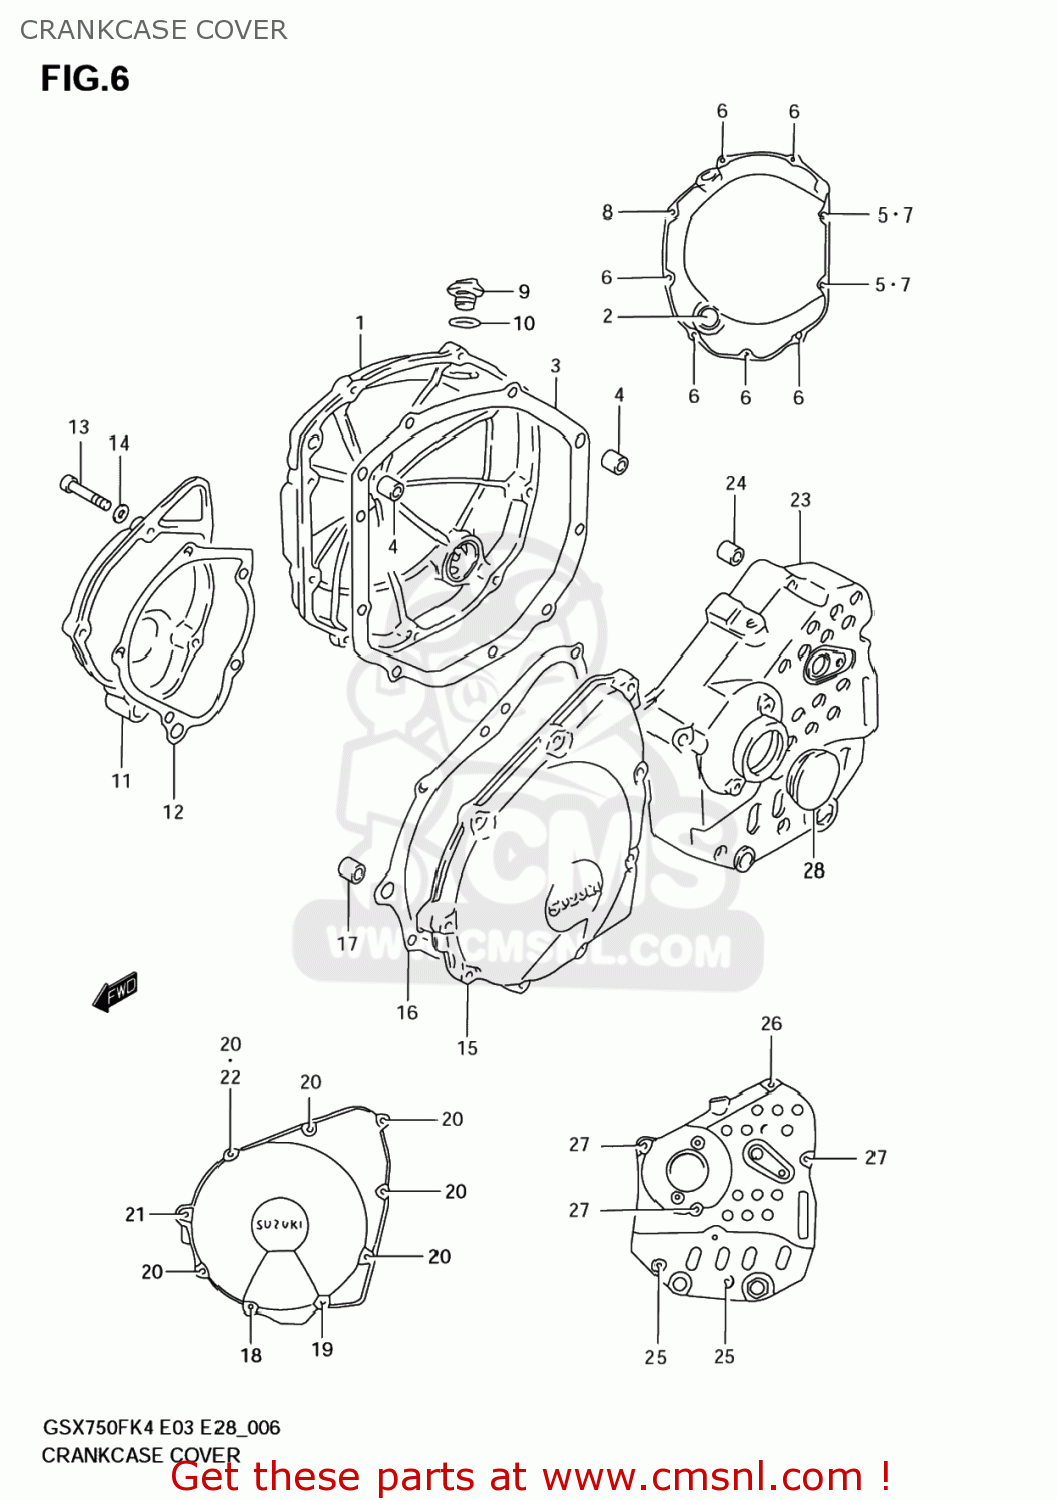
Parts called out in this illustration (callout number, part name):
1	COVER,CLUTCH
2	LENS,OIL LEVEL CHECK
3	GASKET,CL COVER (NAS)
4	PIN
5	GASKET(5.8X13X1.2) (NAS)
6	BOLT(6X25)
7	BOLT
8	BOLT
9	PLUG,ENGINE OIL FILLER
10	O RING(D:3.1,ID:16.8)
11	COVER,SIGNAL GENERATOR
12	GASKET,SIGNAL GEN COVER (NAS)
13	BOLT(6X22)
14	GASKET(5.8X13X1.2) (NAS)
15	COVER,STARTER GEAR
16	GASKET,STARTER GEAR COVER (NAS)
17	PIN(8.4X11X20)
18	BOLT(6X16)
19	BOLT(6X20)
20	BOLT(6X25)
21	BOLT
22	GASKET(5.8X13X1.2) (NAS)
23	COVER,ENGINE SPROCKET
24	PIN
25	BOLT
26	BOLT
27	BOLT
28	CAP(OD:36)
